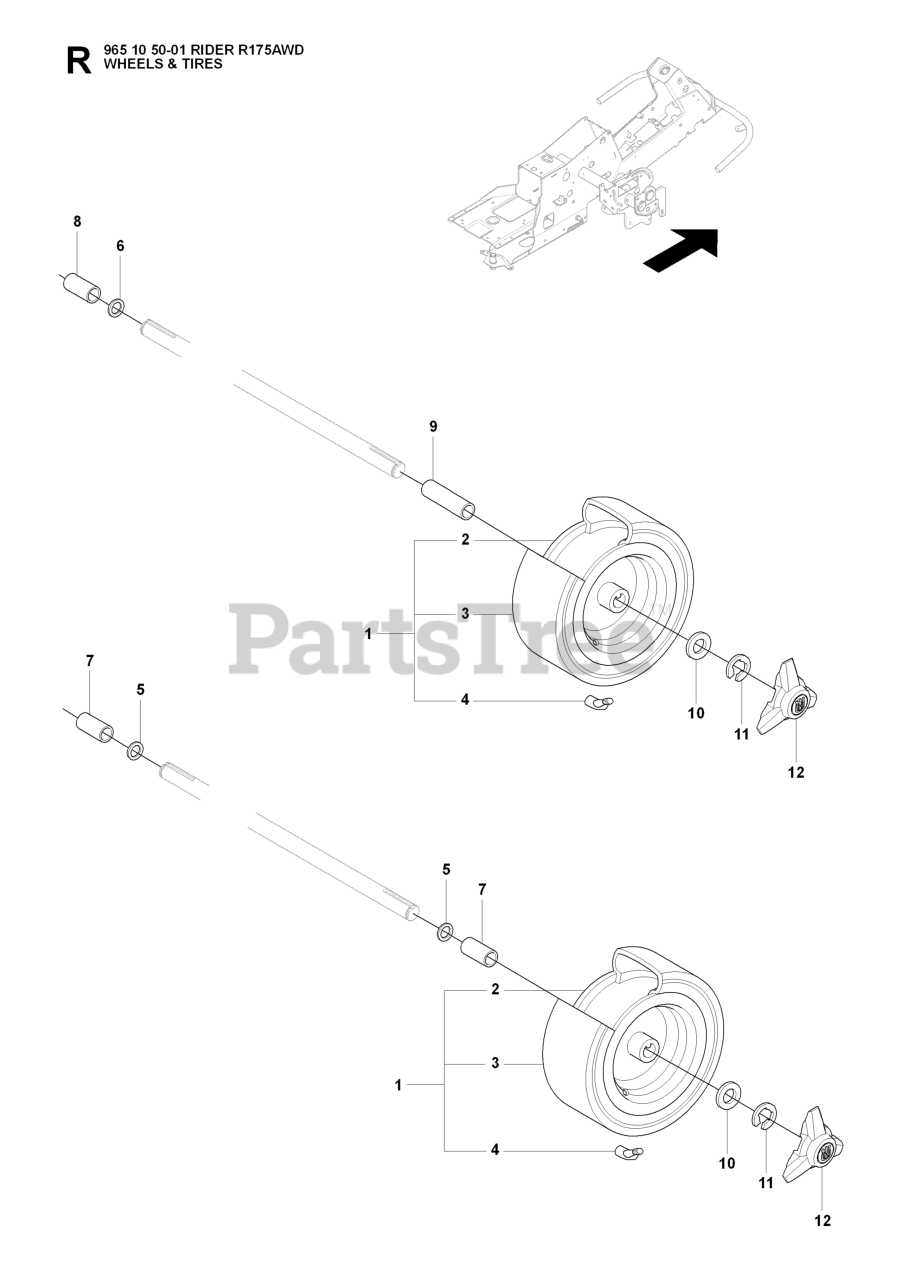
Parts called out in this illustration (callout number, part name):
1	WHEEL
2	RP RIM
7	SPACE SLEEVE
11	RETAINING RING
